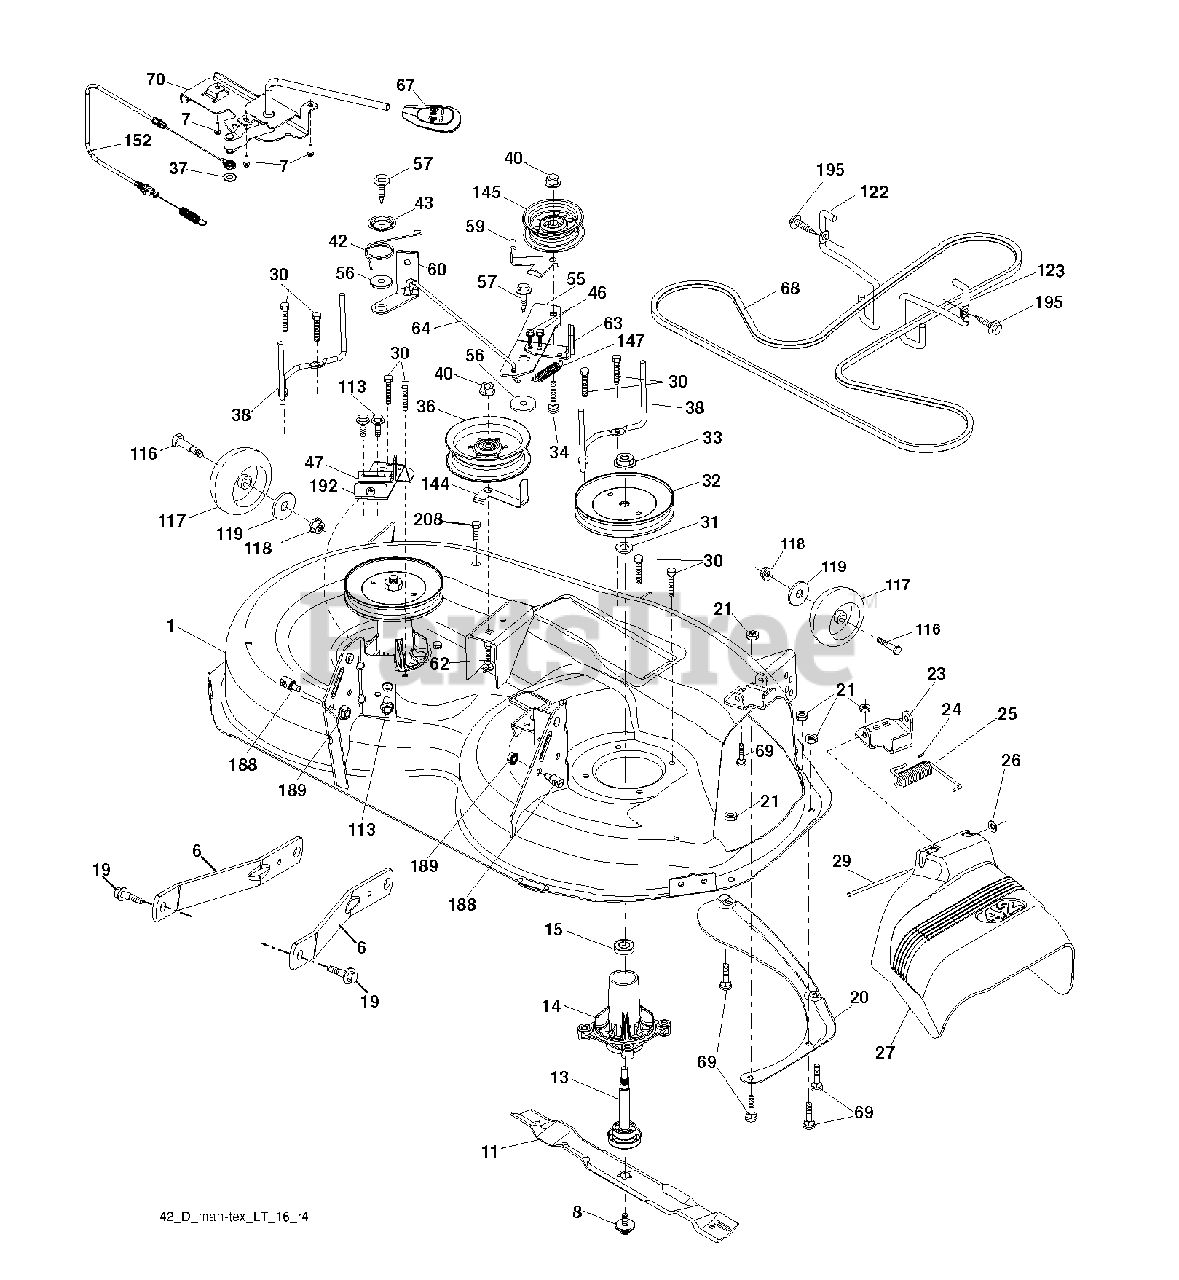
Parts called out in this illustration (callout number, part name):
1	DECK.WELDMENT.42"
6	ARM.SUSPENSION.MOWER.R
7	SCREW.#10 X 0.750.BOS THREAD
8	BOLT.WASHER.ASM.7/16-2
11	42" HI-LIFT BLADE
13	SHAFT.ASM.MDRL.N/GREASE.38
14	HOUSING MANDREL
19	BOLT.SHOULDER
20	BAFFLE.VORTEX
21	LOCKNUT
23	BRKT.DEFLECTOR.38"2005+
24	CAP-SLEEVE LT
25	SPRING.TORSION.DEFLECT
26	NUT PUSH M
27	SHIELD.DEFLECTOR.MOWER.42"BLAC
29	ROD.HINGE
30	SCREW, WASHER HEAD
31	WASHER.SPACER.MANDREL
32	PULLEY.MANDREL.5.438.PD
33	NUT.FLANGE.LOCK.TOP
34	BOLT.3/8-16X1.50
36	PULLEY.IDLER.2006
38	KEEPER.BELT.MANDREL.PULLEY
40	NUT LOCK FLG 3/8-16 UNC
42	SPRING.TORSION.BRAKE
43	SRPING.TORSION.RETAINE
46	SCREW.1/4-20X5/8
47	BRKT.CLUTCH.CABLE
55	IDLER.ARM.42"
56	SPACER.RETAINER
57	SCREW 3/8-16X1
59	GUARD, BELT
60	ARM BRAKE MOWER
62	BOLT
63	ARM BRAKE MOWER
64	LINK BRAKE
67	HANDLE.CLUTCH.CABLE.LT
68	BELT.DECK.DRIVE.42"
69	BOLT
70	CLUTCH.ASM.MANUAL.LT.TEX
113	BOLT.5/16HEX.WHS.HD
117	WHEEL.GAGE.HALF.SPOKED
118	NUT LOCK FLG 3/8-16 UNC
119	WASHER
122	KEEPER BELT ENGINE LH
123	KEEPER BELT RH
144	KEEPER.BELT.MOWER
145	PULLEY.IDLER.48"PRIMARY
147	RETURN SPRING
152	CABLE.CLUTCH.MANUAL.
188	STUD.FASTNER.W/ANTI-ROTATE
189	NUT LOCK HEX FLANGE 5/16-18
192	BRKT.BRAKE.STAND.LH.
195	SCREW, 3/8-16X3/4
208	SCREW 3/8-16X1/2
